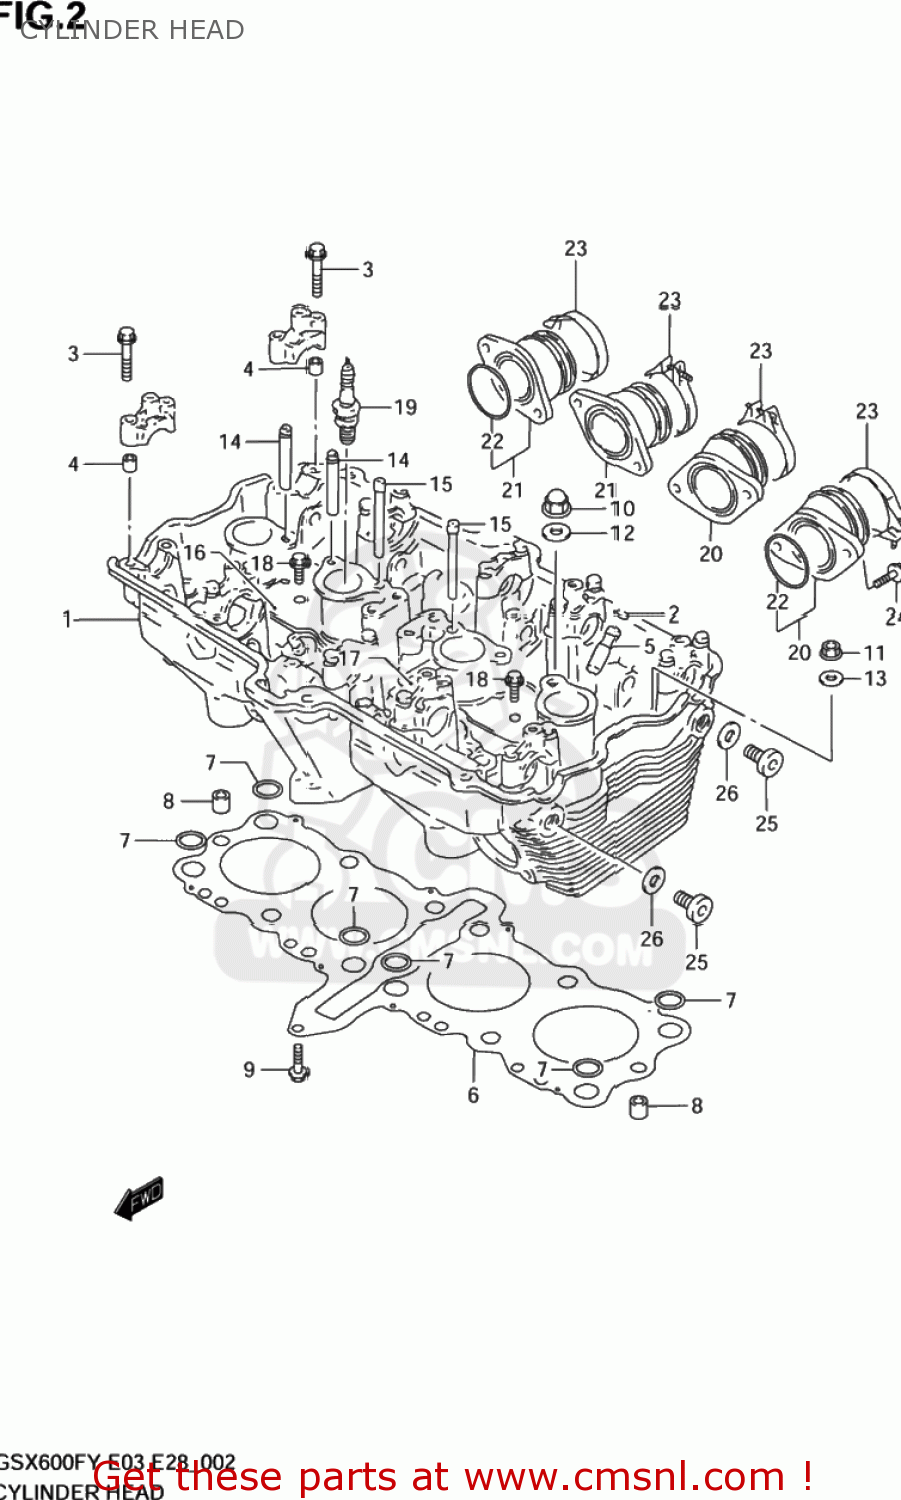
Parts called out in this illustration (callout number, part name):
1	HEAD ASSY,CYLINDER
2	RING,SNAP
3	BOLT(6X39)
4	PIN(6.2X8X11)
5	GUIDE,VALVE
6	GASKET,CYLINDER HEAD (NAS)
7	O RING(D:2.6,ID:12.1)
8	PIN
9	BOLT
10	NUT
11	NUT
12	GASKET(10.2X20X2).3 (NAS)
13	WASHER (10.5X22X2.3)
14	PIPE,OIL NO.1
15	PIPE,OIL NO.3
16	PLATE,OIL PIPE,R
17	PLATE,OIL PIPE,L
18	BOLT
19	PLUG,SPARK(CR9EK)
20	PIPE ASSY,INTAKE NO.1
21	PIPE ASSY,INTAKE NO.3
22	O RING(D:2.4,ID:39.7)
23	CLAMP
24	BOLT MAGNETO S
25	PLUG
26	GASKET(13.8X18.8X4.8) (NAS)
